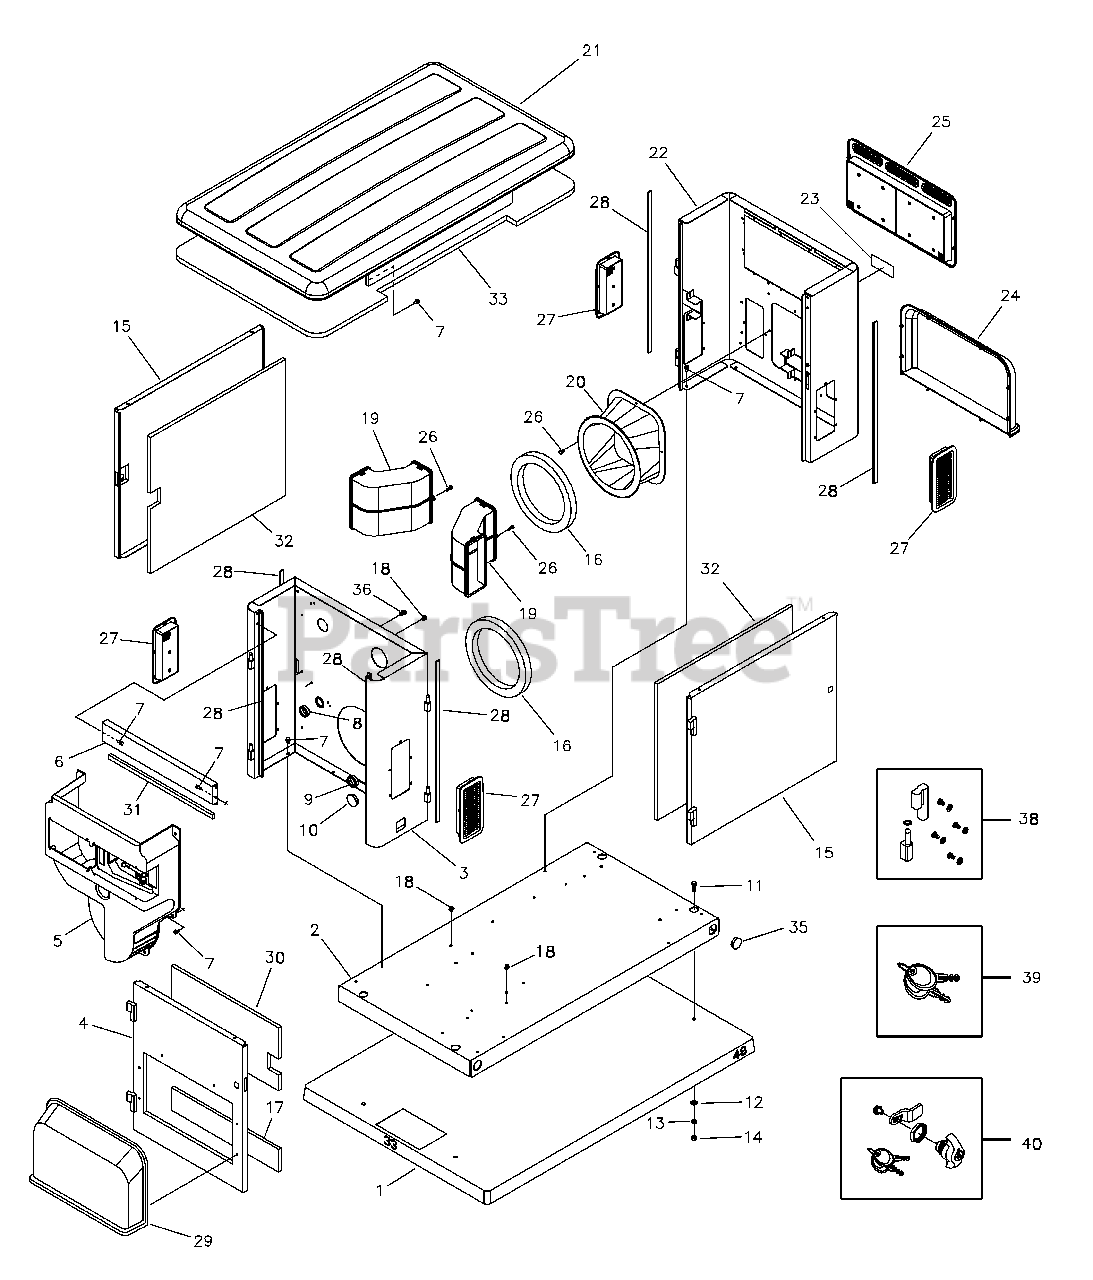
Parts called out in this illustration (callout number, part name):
3	BULKHEAD ASSEMBLY, Engine End
4	DOOR ASSEMBLY, Engine End
6	SUPPORT RAIL ASSEMBLY
7	CAPSCREW, Hex Head, Trilobular, 1/4-20 x 1/2
8	BUSHING, Snap, 1-3/8"
9	BUSHING, Snap, 1-1/2"
11	* CAPSCREW, Hex Head, 3/8-16 x 1
12	* WASHER, Flat, 3/8 - M10
13	* WASHER, Lock, 3/8
14	* NUT, 3/8-16
16	SEAL, Foam, Engine Air
17	INSULATION, Engine Door, Bottom
18	MOUNT, Tie Wrap
19	DUCT, Rubber Alternator
20	ADAPTER, Alternator
21	ROOF ASSEMBLY, With Siderails
22	BULKHEAD ASSEMBLY, Alternator End
23	DECAL, Caution Hot Muffler
24	COVER, Air Intake Alternator
29	COVER, Air Intake Engine
30	INSULATION, Engine Door, Top
32	INSULATION, Front/Rear Door
33	INSULATION, Roof
34	DECAL
